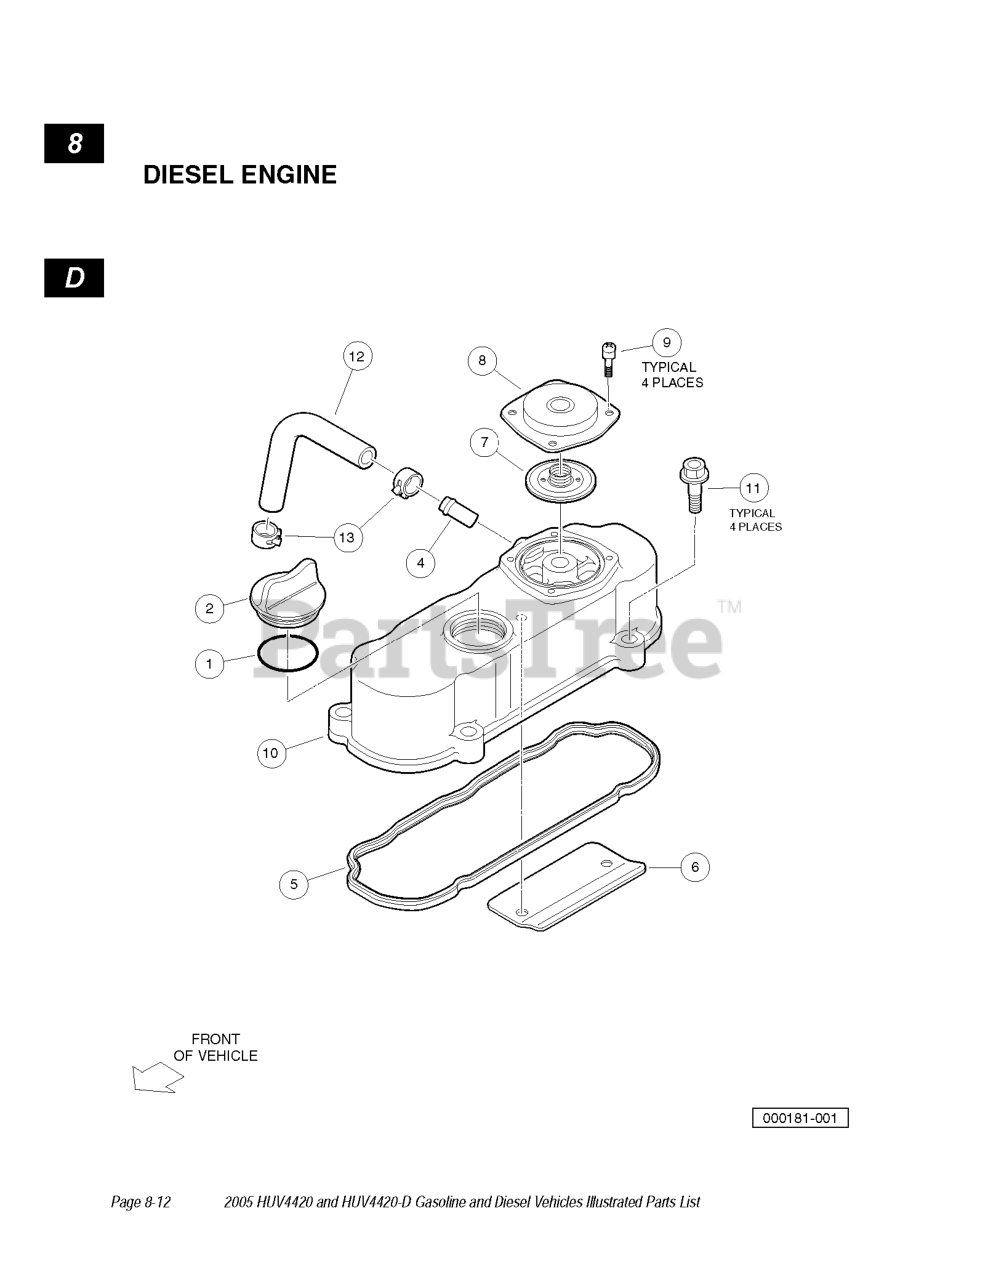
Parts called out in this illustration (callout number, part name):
1	O RING, 30X36
2	PLUG, OIL FILLER
3	ASSY-CYL HEAD COVER
4	PIPE-BREATHER
5	GASKET-HEAD COVER
6	SHIELD-BREATHER
7	VALVE-BREATHER
8	COVER-BREATHER
9	SCREW-BREATHER
11	BOLT-CYL HEAD COVER
12	TUBE, BREATHER
13	CLAMP-BRTHR TUBE
